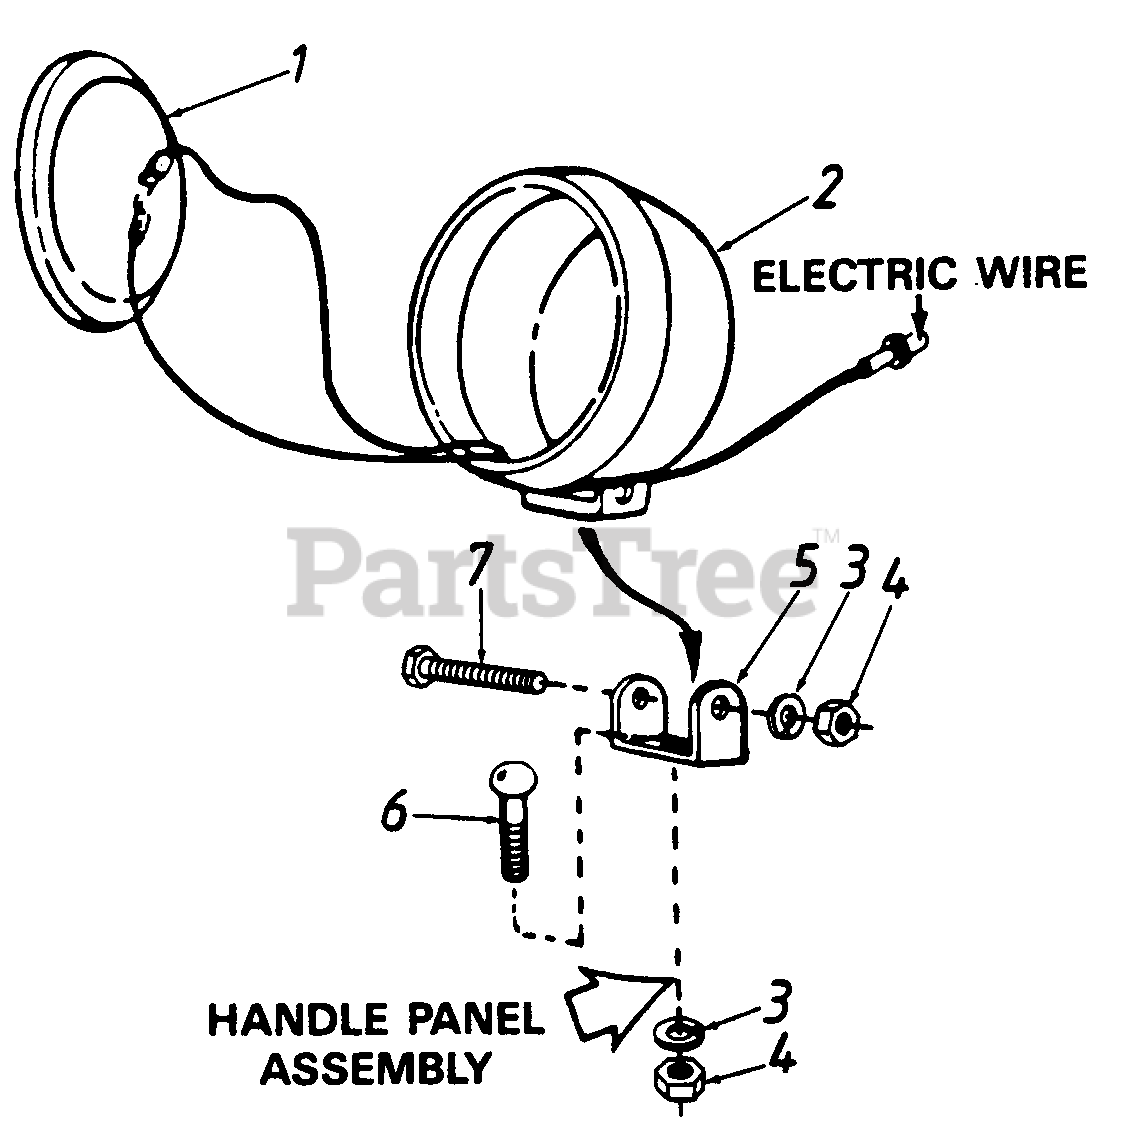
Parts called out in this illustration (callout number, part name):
1	Sealed Beam Headlight
2	Lamp Assembly
3	L.-Wash. 5/16" I.D.
4	Hex Nut 5/16-18 Thd.
5	Lamp Mounting Bracket
6	Carriage Bolt 5/16-18 x 1" Lg
7	Hex Bolt 5/16-18 x 2" 4.
